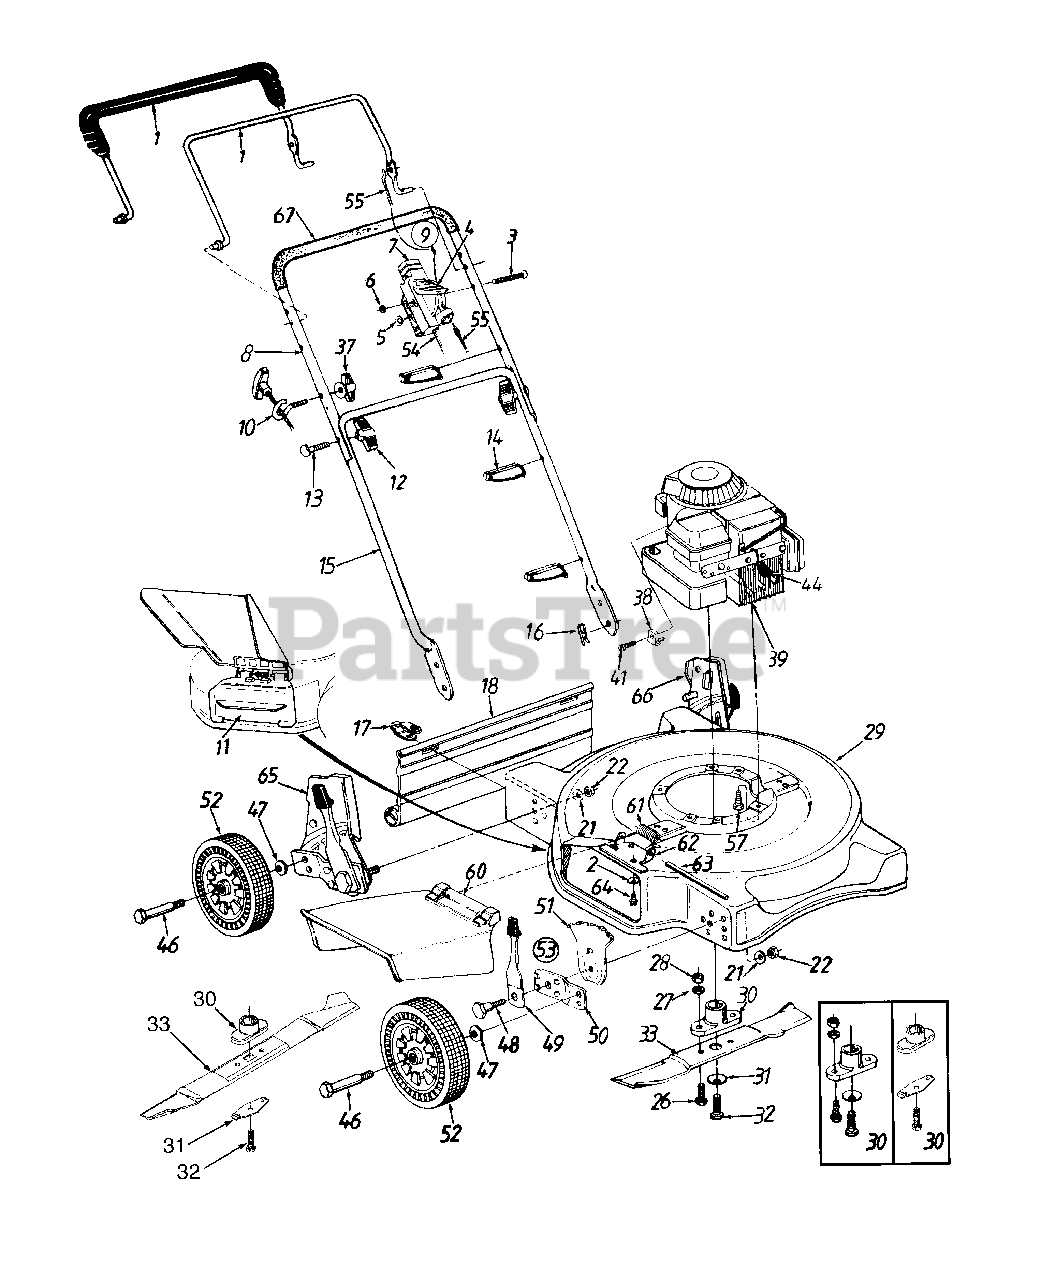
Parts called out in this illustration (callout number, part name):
2	Bell-Wash. 1/4" I.D.
3	Oval C-Sunk Mach. Scr.
4	Throttle Lever
5	Spr. Wash. .66" I.D.
6	Hex L-Nut 1/4-20 Thd.
7	Throttle Body
10	Rope Guide
11	Mulching Plug
12	Hand Knob
13	Curved Hd. Bolt 5/16-18 x 2" Lg.
14	Cable Tie
16	Hairpin Cotter
17	Hinge Clip
18	Rear Flap (20")
21	Bell-Wash. .39" I.D. x 1.38"
22	Hex Nut 3/8-16 Thd.
26	Hex Bolt 3/8-24 x 1" Lg.
27	L-Wash. 3/8" I.D.
28	Hex Nut 3/8-24 Thd.
31	Support, Bell-Blade
32	Hex Bolt 3/8-24 x 1.5" Lg.
33	20" Blade
37	Wing Nut 1/4-20 Thd.
38	Cable Clamp
39	Engine
41	Hex Wash. Hd. Tap Scr. #10-32 x .62 Lg. (B&S)
44	Spark Plug Boot
46	Axle Bolt
47	Bell-Wash. .400" I.D. x .88"
48	Shld. Bolt .50" Dia. x .357"
49	Spring Lever Ass'y. w/Knob
51	Height Adj. Plate
52	Wheel Ass'y. Comp.
53	Height Adj. Ass'y. Comp.-R.F.
54	Throttle Cable-51"
55	Control Cable-39"
57	Hex L-Wash. Hd. Scr. 3/8-16 x 1.0" Lg.
60	Chute Deflector Ass'y.
61	Torsion Spring
62	Adapter Plate
63	Hinge Pin
64	Hex Self-Tap Scr. 1/4-20 x .5"
67	Foam Grip
